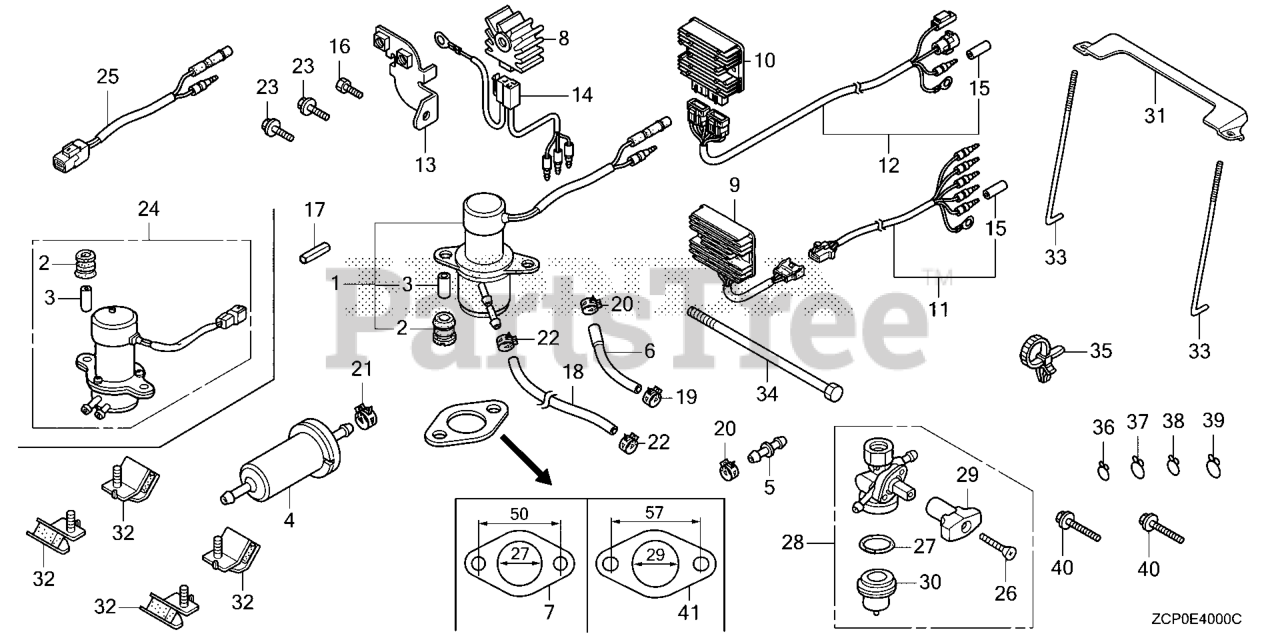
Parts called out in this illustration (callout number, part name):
7	GASKET, EX. PIPE
9	RECTIFIER ASSY., REGULATOR (20A)
11	SUB-WIRE HARNESS ASSY.
15	PLUG, CONNECTOR (OUTER) (ENGINE NO.)
